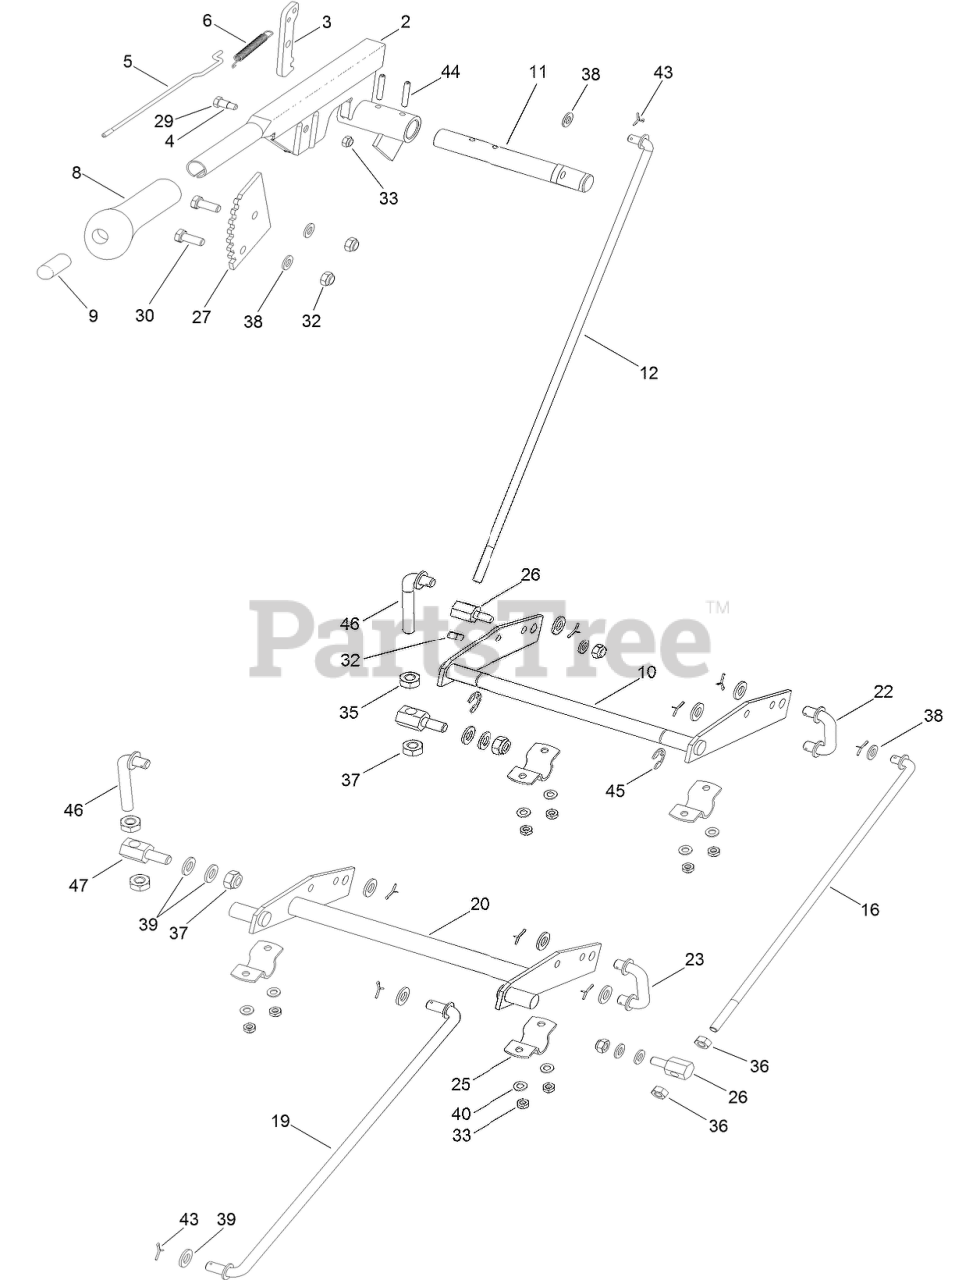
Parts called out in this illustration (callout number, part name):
2	LEVER-ARM
3	RATCHET-PLATE, PIVOT
4	BUSHING
5	ROD-CONNECTION
6	SPRING
8	GRIP-HANDLE
9	BUTTON-PLUNGER
10	HANGER-REAR
11	SHAFT-ADJUSTMENT, HEIGHT
16	ROD-LINKAGE
20	HANGER-FRONT
22	DECK LINK, U-SHAPE, 50
23	DECK LINK, U-SHAPE, 55
26	TRUNNION
27	GEAR-SEGMENT, DECK LIFT
29	SCREW-HH
30	SCREW-HH
32	NUT-LOCK, NI
33	NUT-LOCK
35	NUT-HEX
36	NUT-HEX
37	NUT-LOCK, NI
38	WASHER-PLAIN
39	WASHER-FLAT
40	WASHER
43	PIN-COTTER
44	PIN-SPRING
45	E-CLIP
46	LINK-DECK, L-SHAPE (ADJUSTABLE)
47	TRUNION
